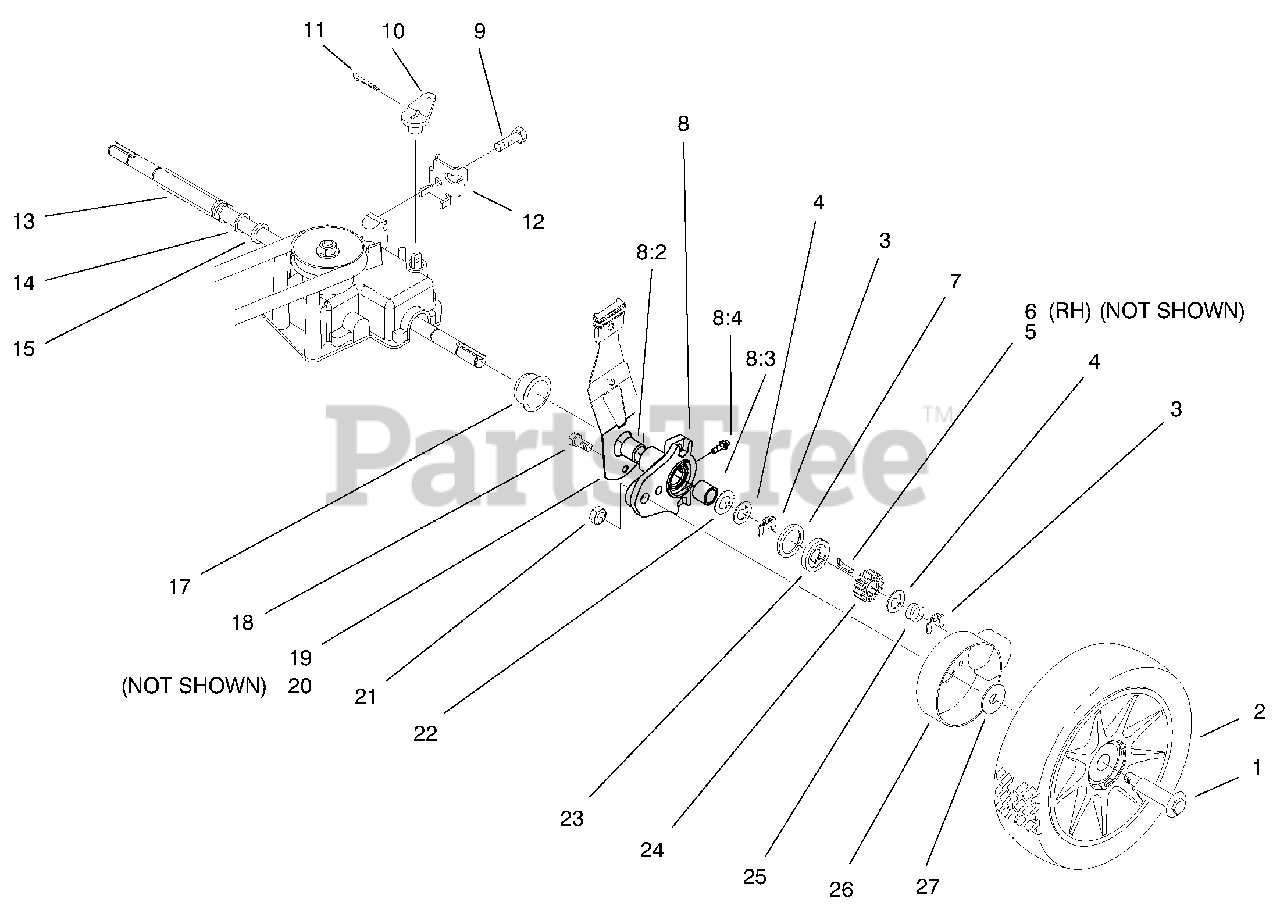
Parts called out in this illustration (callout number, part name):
1	Bolt-Shoulder
2	ASM-Whl
3	Ring-Retaining
4	Washer-Thrust
5	Key-Rocking LH
6	Key-Locking RH
7	Ring-Friction
8	ASM-Hgt Adj Arm
8:4	Fitting-Grease
9	Screw-TAP
10	Lever-Shift
11	Pin-Cotter
12	Retainer-Cable
13	Cover-Drive Shaft
15	Washer-Flat
19	ASM-Spring Arm
20	ASM-Spring Arm
21	Nut-Lock
22	Washer-Thrust
24	Gear-Pinion
25	Spring-Compression
26	Cover-Wheel
27	Washer-Stepped
